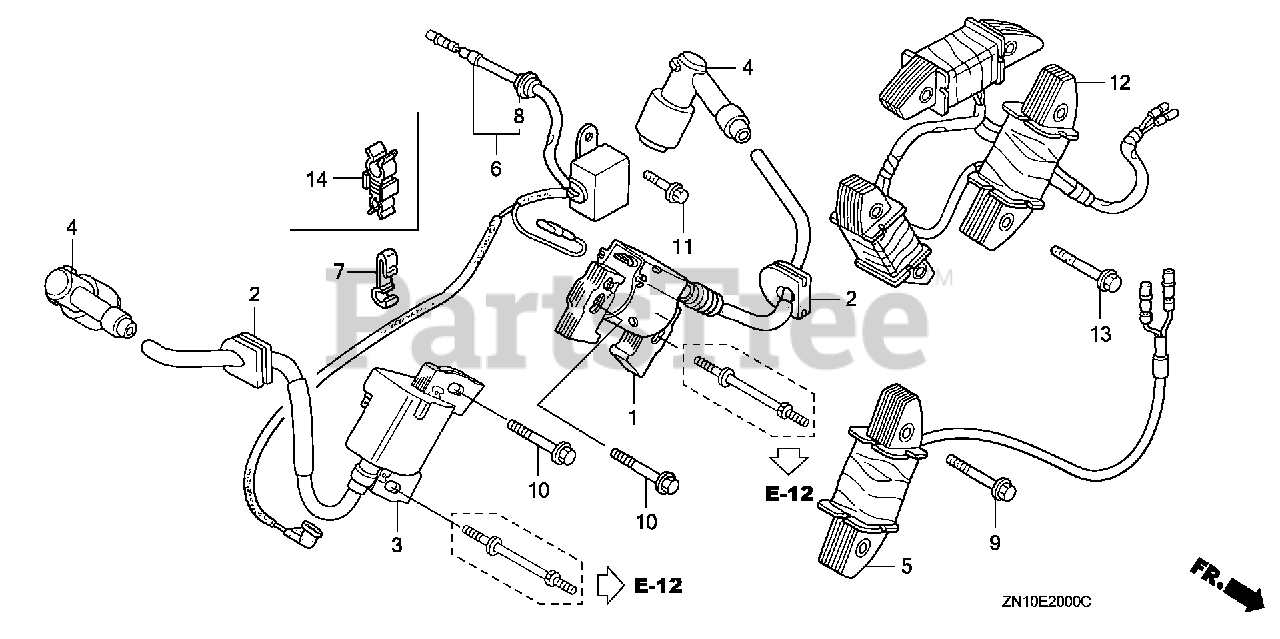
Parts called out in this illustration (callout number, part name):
1	COIL ASSY., IGNITION (200MM) (BLACK) (L. SIDE)
2	GROMMET, IGNITION WIRE
3	COIL ASSY., IGNITION (215MM) (GRAY) (L. SIDE)
4	CAP ASSY., NOISE SUPPRESSOR
5	COIL ASSY., CHARGE (12V/3A)
6	DIODE ASSY., ENGINE STOP
8	GROMMET, TOOL
9	BOLT, FLANGE (6X35)
10	BOLT, FLANGE (6X32)
11	BOLT, FLANGE (6X8)
